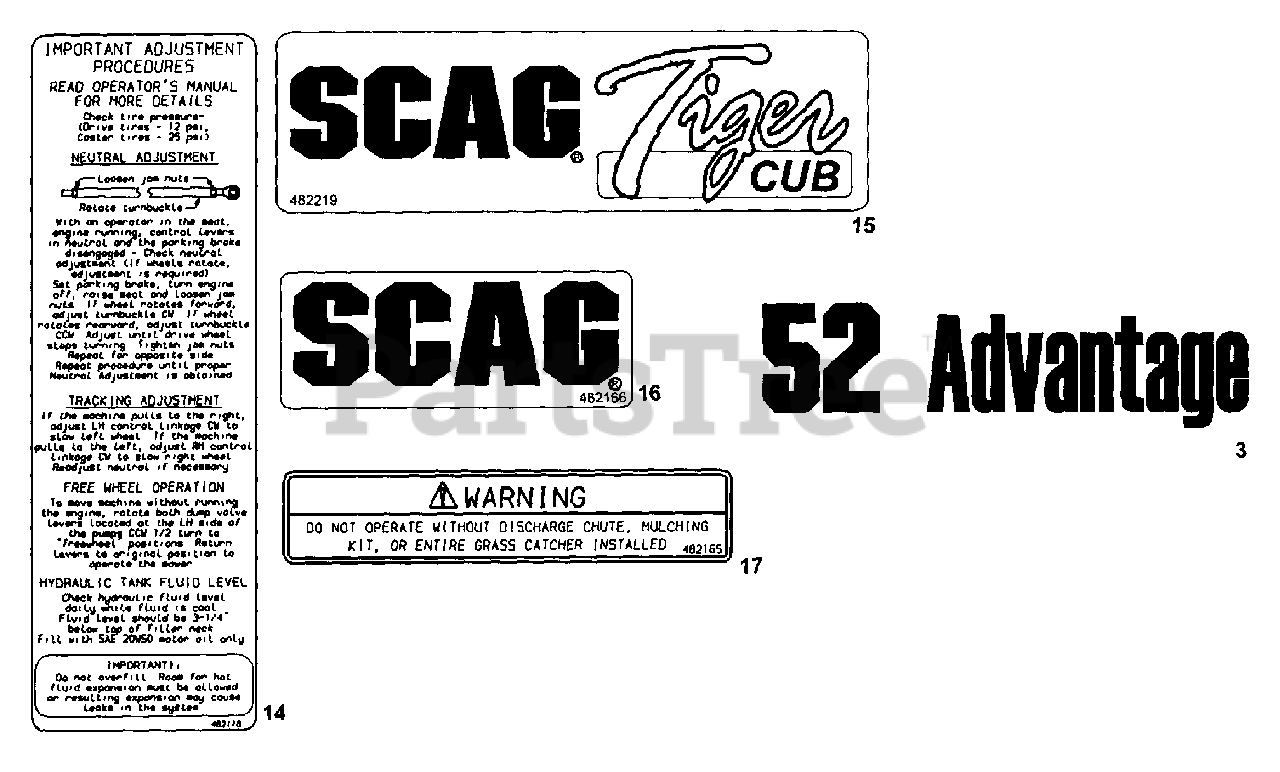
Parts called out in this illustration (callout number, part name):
3	Decal, 40
14	Decal, Seat Support
15	Decal, Rear Bumper
16	Decal, Front Footplate
17	Decal, Discharge Chute
